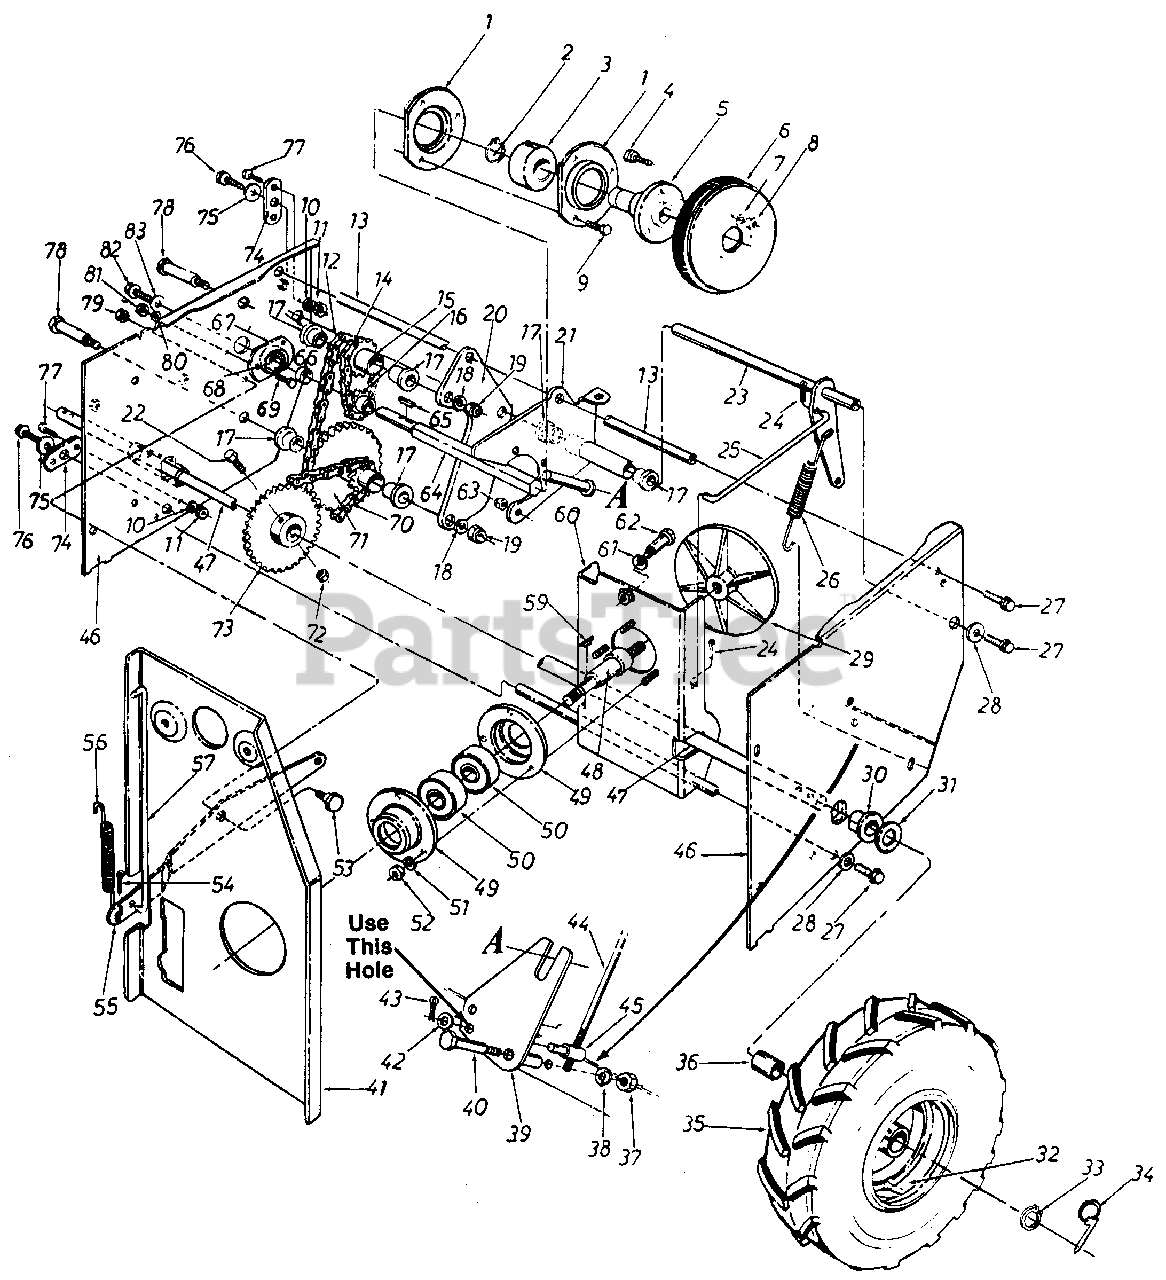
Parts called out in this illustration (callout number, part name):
1	Bearing Housing
2	Snap Ring-1.0" Dia.
3	Ball Brg. .25MM x 52MM x 15MM Thk.
4	Hex Sems Bolt 5/16-18 x .75" Lg.*
5	Friction Wheel Adapter
6	Friction Wheel Ass'y.
7	L-Wash. 5/16" I.D.
8	Hex Nut 5/16-18 Thd.
9	Hex Bolt 1/4-28 x .62" Lg.
10	L-Wash. 1/4" I.D.
11	Hex Nut 1/4-20 Thd.
12	#41 Chain-1/2" Pitch x 43 Links
12	Master Link
13	Sliding Support Axle
14	#41 Chain-1/2" Pitch x 19 Links
14	Master Link
15	9 and 14 Teeth Sprocket Hub Ass'y.
16	8 Teeth Sprocket
17	Flange Bearing .63" I.D.
18	L-Wash. 3/8" I.D.-Heavy Duty
19	Hex L-Jam Nut 3/8-24 Thd.
22	Hex Bolt 5/16-24 x 1.75" Lg.
23	Drive Ciutch Brkt. Ass'y.
24	Inter. Cot. Pin 5/16" Dia.*
25	Drive Clutch Rod .31" Dia. x 7.38" Lg.
26	Extension Spring .73" O.D. x 4.31" Lg.
27	Hex L-Bolt 5/16-18 x .62" Lg.
28	Fl-Wash. .345" I.D. x .75" O.D.
29	Aluminum Drive Plate
30	Flange Brg. w/ Flats 1" I.D.
31	Fl-Wash. .62" I.D. x 1.25" O.D.
32	Tubeless Air Valve
33	Snap Ring 1" Shaft
34	Klick Pin Ass'y.
35	Wheel Ass'y. Comp. 16 x 4.5-L.H.
35	Wheel Ass'y. Comp. 16 x 4.5-R.H.
35	Tire Only 16 x 4.5
35	Rim Only-8 x 2.75
36	Bearing 1.0" I.D. x 1.12 O.D. x 1.0" Lg.
37	Hex Jam Nut 3/8-16 Thd.
38	L-Wash. 3/8" I.D.
41	Engine Brkt. Ass'y.
42	Fl-Wash. .344" I.D. x .62" O.D.
43	Cotter Pin 3/32" Dia. x .75" Lg. *
44	Shifting Rod
45	Adjustment Ferrule
46	Frame Ass'y.
47	Free Wheeling Axle
48	Drive Plate Spindle
49	Bearing Housing
50	Ball Brg. .787" I.D. x 1.85" O.D.
51	L-Wash. 5/16" I.D.*
52	Hex Nut 5/16-18 Thd.*
53	Shld. Bolt .625" Dia. x .170" Lg.
54	Inter. Cotter Pin 5/16" Dia.*
55	Auger Clutch Brkt.
56	Extension Spring .38" O.D. x 3.18" Lg.
57	Auger Clutch Rod .31" Dia. x 10.62" Lg.
59	#61 Hi-Pro Key 3/16" x 5/8" Dia.
62	Shld. Bolt
63	Hex Ins. Jam Nut 1/4-28 Thd.
64	Hex Shaft
65	#9 Hi-Pro Key 3/32" x 5/8" Dia.
66	Spacer .51" I.D. x .69" O.D.
67	Bearing Housing
68	Ball Bearing
69	Hex Bolt 1/4-20 x .62" Lg.*
70	#420 Chain .50" Pitch x 37 Links
70	Master Link
71	9 and 32 Teeth Sprocket Hub Ass'y.
72	Hex L-Nut 5/16-24 Thd.
73	28 Teeth Sprocket Hub Ass'y.
74	Pivot Axle Brkt.
75	Fl-Wash. .345" I.D. x .75" O.D.
76	Hex L-Bolt 5/16-18 x .62" Lg.
77	Hex Bolt 1/4-20 x .62" Lg.*
78	Sprocket Hub Tubing 1.880" Lg.
79	Hex Cent. L-Nut 3/8-16 Thd.
80	L-Wash. 1/4" I.D.*
81	Hex Nut 1/4-20 Thd.*
82	Hex L-Bolt 5/16-18 x .62" Lg.
83	Fl-Wash. .345" I.D. x .75" O.D.
